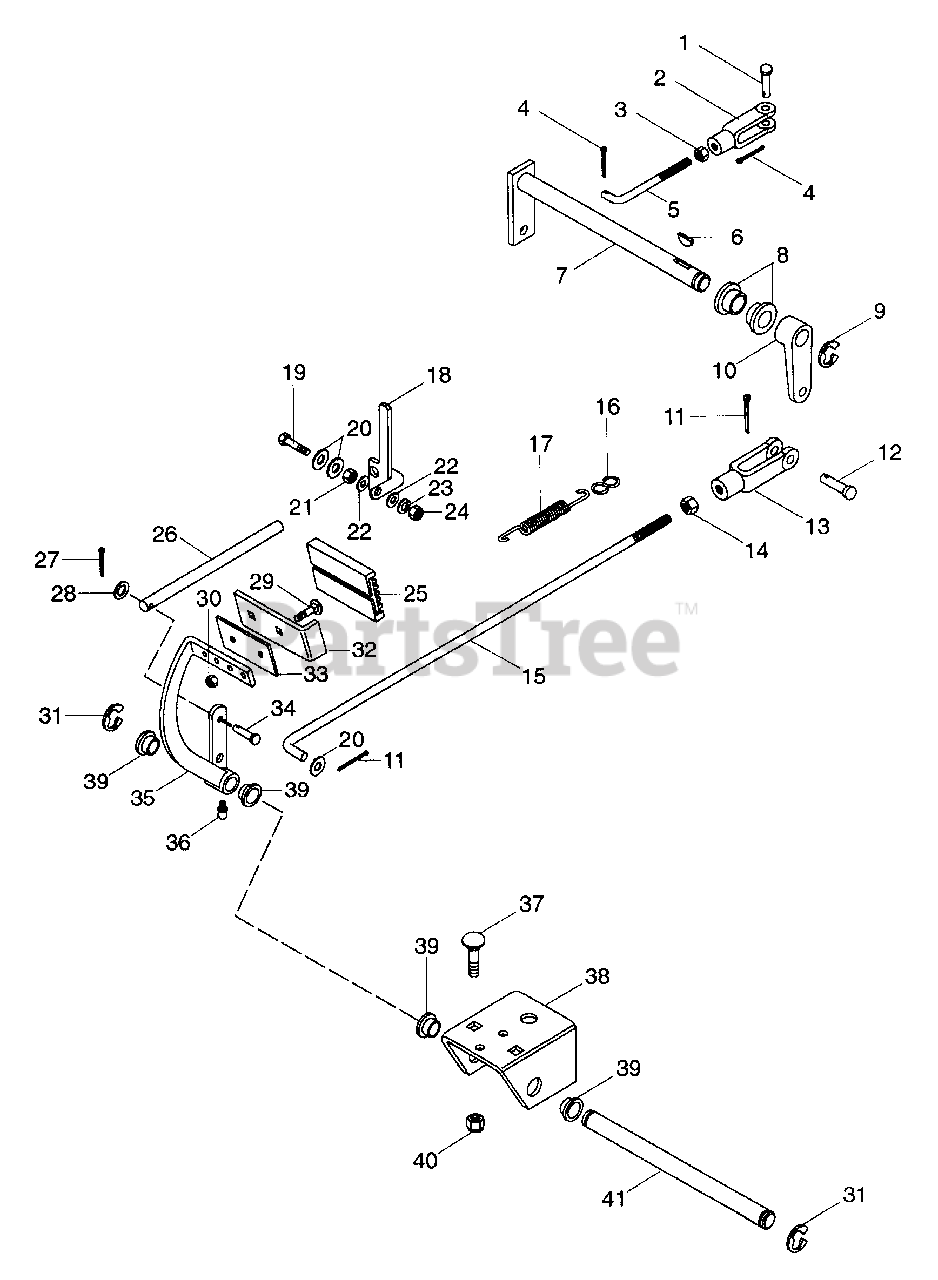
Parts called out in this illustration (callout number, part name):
1	Pin-Clevis .312 x .822
2	Yoke .31-24 x 2.250
3	Nut-Hex .312-24 Grade 2
4	Pin-Cotter .09 x .75
5	Rod, Parking Brake
6	Key, Woodruff .19 x .75
7	Weldment, Brake Cross Shaft
8	Bushing-Flange .762 x 1.0 x .580 x 1.48
9	Ring-Retaining-External .574 x .050
10	Lever, PTO
11	Pin-Cotter .12 x .75
12	Pin-Clevis .375 x .948
13	Clevis .38-24 Adjustable
14	Nut-Jam .375-24
15	Rod, Brake
16	Clip, Spring
17	Spring-Tens .095 x .500 x 5.5
18	Arm, Parking Brake Lock
19	Bolt-Hex .38-16 x 1.25 Grade 5
20	Washer-Flat-Steel .406 x .812 x .065
21	Nut-Jam .375-16
22	Washer-Flat-Nylon .375 x .75 x .060
23	Washer-Lock .375 x .094
24	Nut-Locking-Center .625-10 Grade 2
25	Pad, Pedal
26	Rod
27	Pin-Cotter .062 x .75
28	Washer-Flat-Steel .281 x .62 x .065
29	Bolt-Round Head Square Neck .25-20 x 1.25
30	Nut-Locking-Nylon .250-20 Grade 2
31	Ring-Retaining-External .625 x .042
32	Pedal, Brake
33	Plate, Brake
34	Pin-Clevis .25 x 1.13
35	Weldment, Brake Pedal
36	Fitting-Lube .25-28 x .256
37	Bolt-Round Head Square Neck .38-16 x .75 Grade 1
38	Bracket, Brake Pedal
39	Bushing-Flange .630 x 1.000 x .625
40	Nut-Locking-Nylon .375-16 Grade 2
41	Shaft, Brake Pedal Mounting
